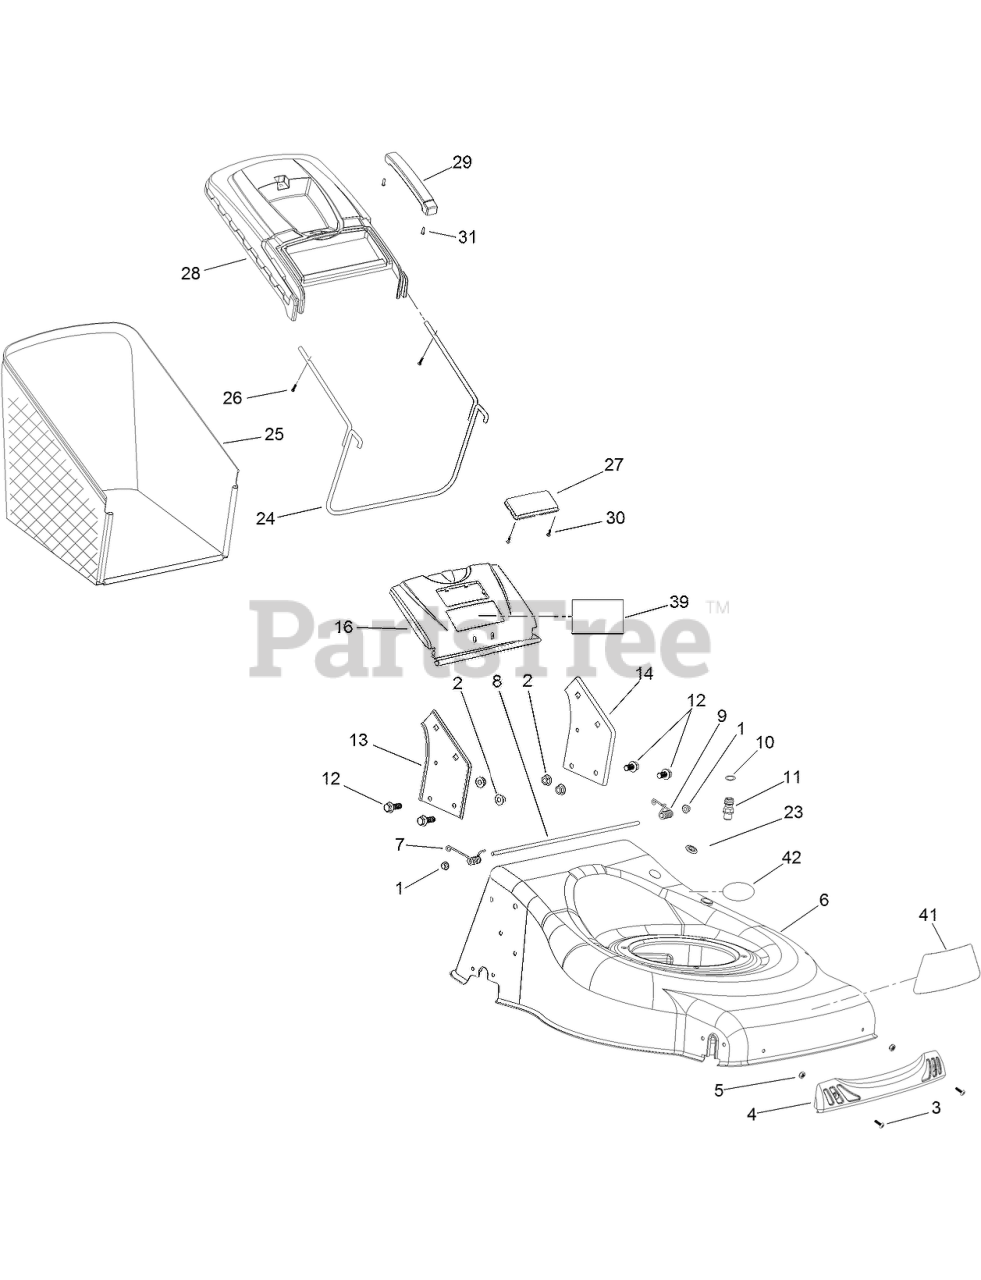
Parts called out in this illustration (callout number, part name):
1	NUT-LOCK, FLANGE
2	NUT-LOCK, FLANGE
3	SCREW-TOOTH
4	BUMPER-FRONT
5	NUT-LOCK
7	SPRING-TWIST, RH
8	ROD-SPRING, REAR DEFLECTOR
9	SPRING-TWIST, LH
10	O-RING
11	PORT-WASH
12	BOLT-HH, FLANGE
13	BRACKET-HANDLE, RH
14	BRACKET-HANDLE, LH
16	DEFLECTOR-REAR
23	CAP-END
24	FRAME-BAG, GRASS
25	BAG-GRASS
26	SCREW-SELF DRIVING
27	WINDOW-TRANSPARENCY
28	CATCHER-GRASS
29	HANDLE-CATCHER, GRASS
30	SCREW-SELF DRIVING
31	SCREW-SELF DRIVING
39	DECAL-SAFETY
41	DECAL-SHROUD
42	DECAL-PORT, WASHOUT
